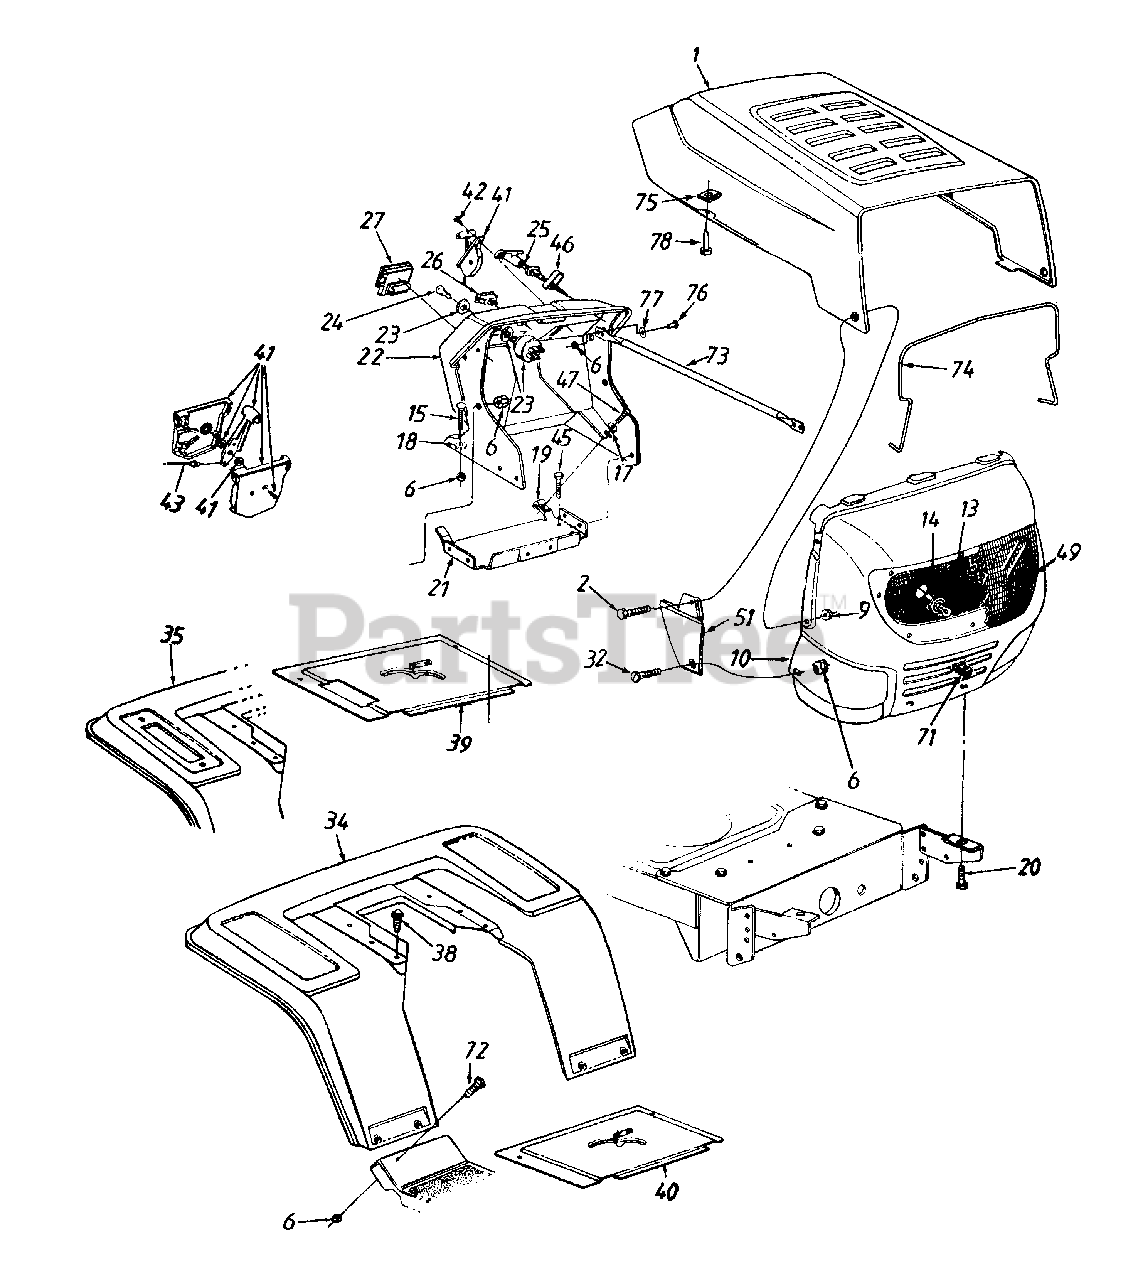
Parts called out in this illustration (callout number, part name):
6	Hex Sems Nut 1/4-20 Thd.
9	Flange L-Nut 1/4-20 Thd.
13	Lamp
14	Socket
15	Carriage Bolt 1/4-20 x .75" Lg.
17	Fl-Wash. .281" I.D. x .73" O.D.
18	Bolt Retainer 1/4" I.D.
19	Speed Nut 1/4-20 Thd.
20	Hex Bolt 5/16-18 x .75" Lg.
23	Ignition Switch
24	Ignition Key
25	i Choke Control 23" Lg.
26	Light Switch
27	Ammeter
32	Pan Hd. Scr. 1/4-20 x .75" Lg.
41	Throttle Box Ass'y.
42	Truss Mach. AB-Tap Scr.#10 x .5" Lg.
43	Throttle Control Wire 18.5" Lg.
45	Hex Wash. Hd. B-Tap Scr.5/16-18 x .5" Lg.
46	Choke Retainer
47	Hex TT-Tap Scr. 1/4-20 x .75"Lg.
49	Lens
72	Truss Mach. Scr. 1/4-20 x .5" Lg.
75	Speed Nut
76	Hex Bolt 1/4-20 x 5/8" Lg.
77	Fl-Wash. .283" I.D. x .75" O.D.
78	Hex Hd. Tap Scr. #10-16 x .75" Lg.
